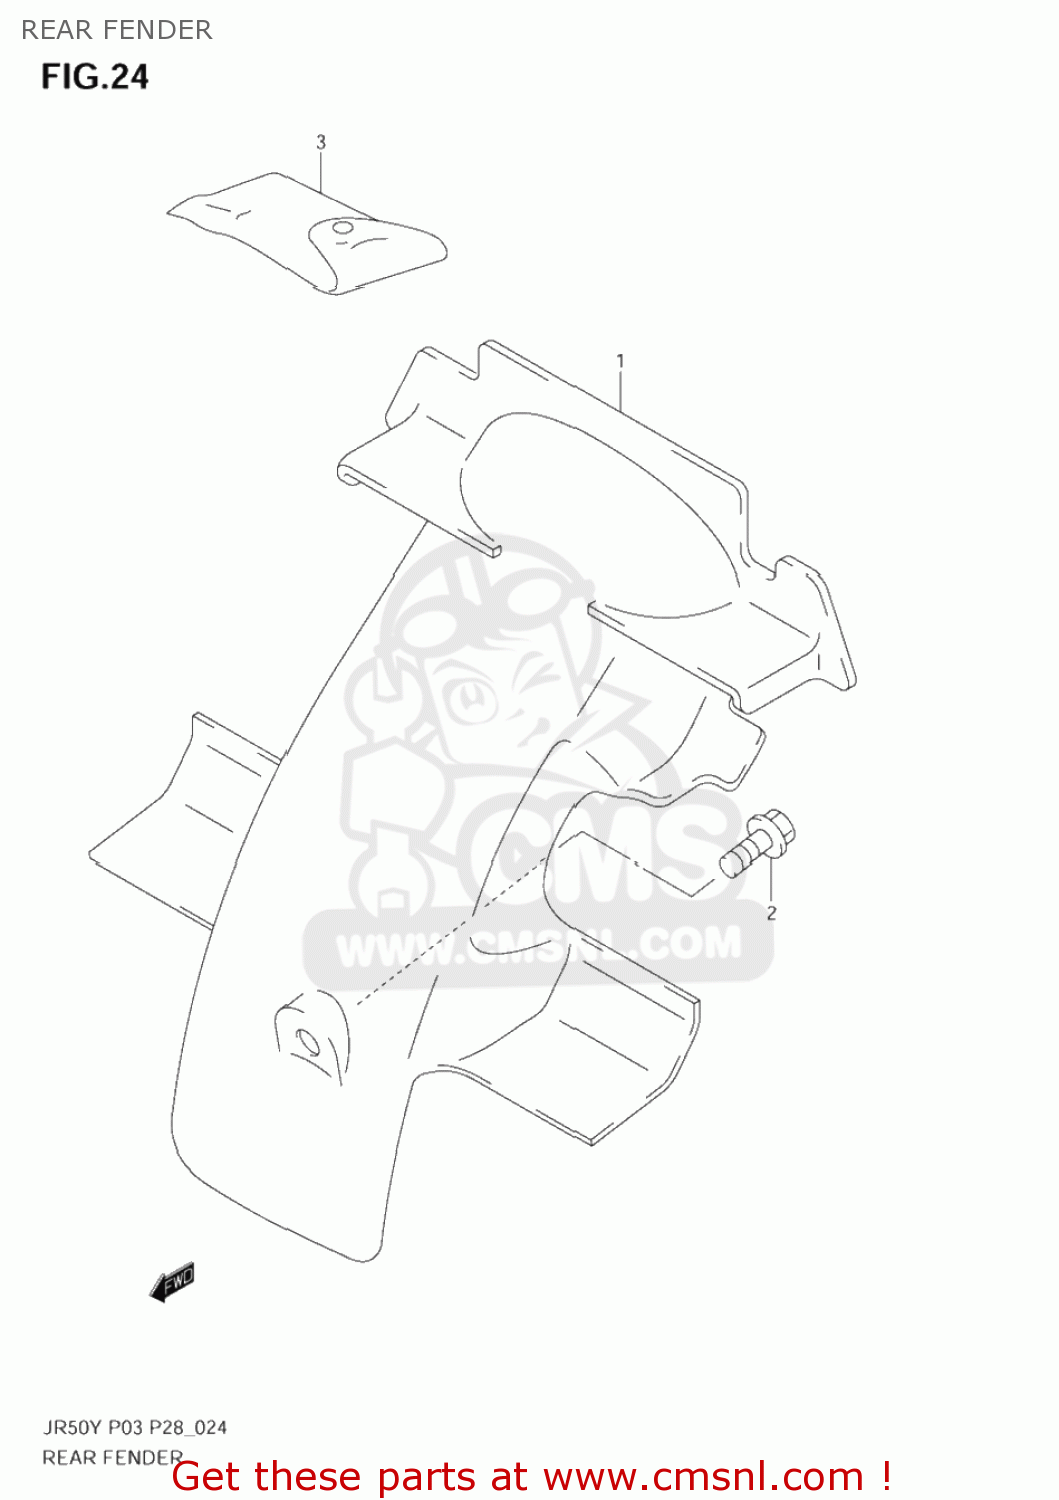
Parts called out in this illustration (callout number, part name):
1	FENDER,RR FR
2	BOLT
3	TOOL ASSY
